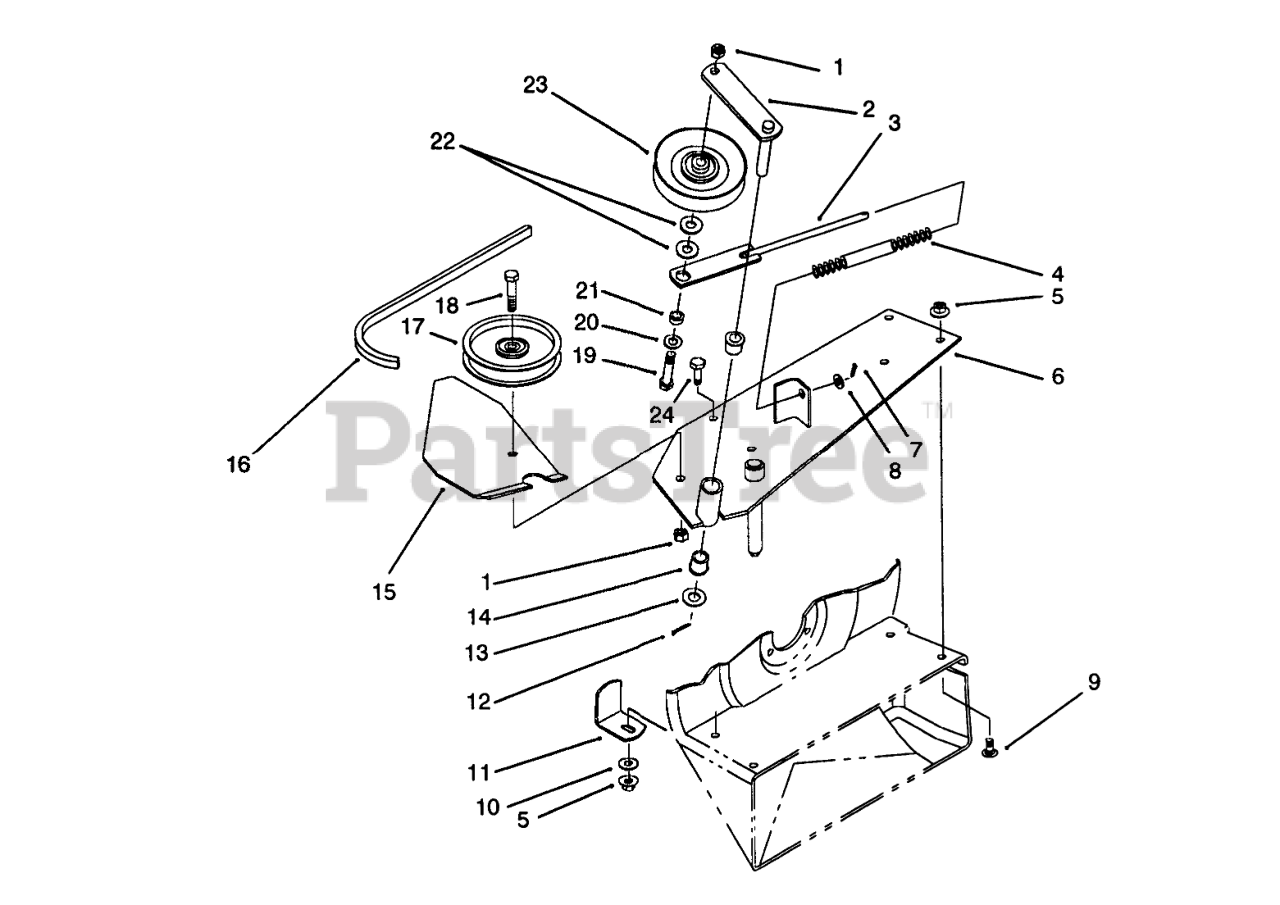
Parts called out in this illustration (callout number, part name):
1	NUT-LOCK, NI
2	IDLER ARM ASM
3	SPRING-ROD
4	SPRING-COMPRESSION
5	NUT-HF
6	BLOWER-MTG ASM
7	PIN-COTTER
8	WASHER-PLAIN
9	BOLT-CARR
10	WASHER-FLAT
11	BRACKET-SUPPORT, HOUSING
12	PIN-COTTER
13	WASHER-FLAT
14	BUSHING
15	SHIELD SUPPORT B
16	V-BELT
17	Pulley
18	SCREW-HH
19	SCREW-HH
20	WASHER-FLAT
21	SPACER
22	WASHER-FLAT
23	"V" Pulley
24	SCREW-HH
